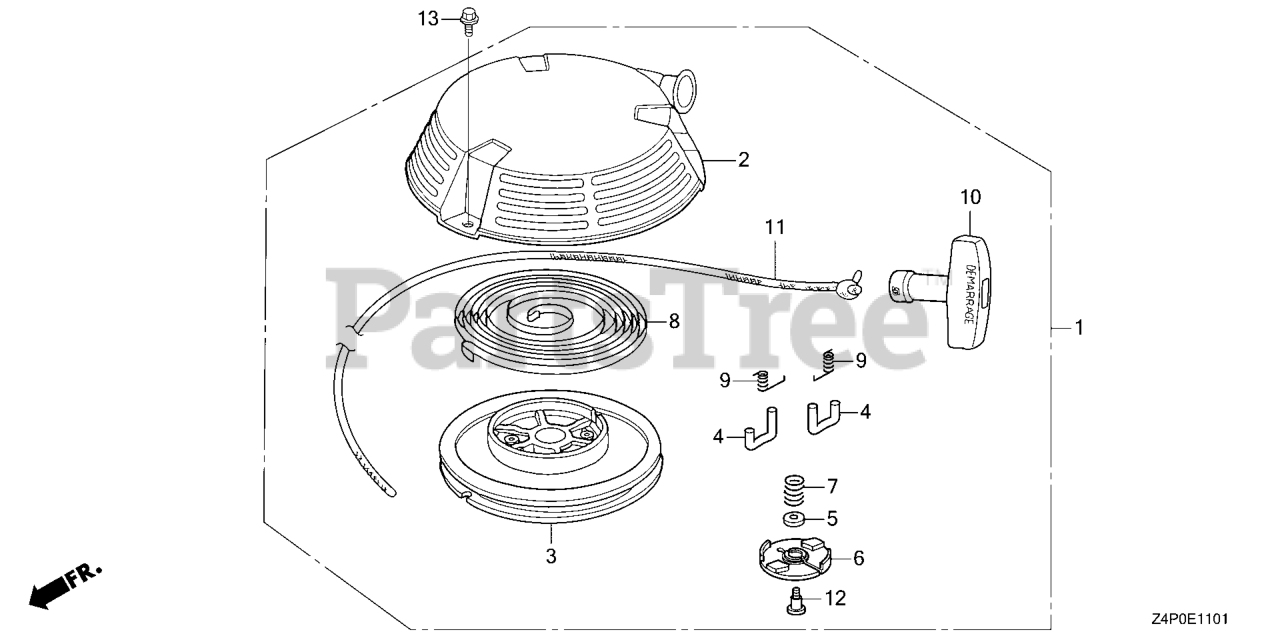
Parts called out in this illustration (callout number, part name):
1	STARTER ASSY. *NH1*
1	STARTER ASSY., RECOIL *R280* (LONG ROPE) (POWER RED)
2	CASE, RECOIL STARTER *NH1* (BLACK)
2	CASE, RECOIL STARTER *R280* (POWER RED)
3	REEL, RECOIL STARTER (BLACK)
4	RATCHET, STARTER
5	PLATE, FRICTION
6	GUIDE, RATCHET
7	SPRING, FRICTION
8	SPRING, RECOIL STARTER
9	SPRING, RETURN
10	KNOB, RECOIL STARTER
11	ROPE, RECOIL STARTER (LONG TYPE)
12	SCREW, SETTING
13	BOLT, FLANGE (6X8)
